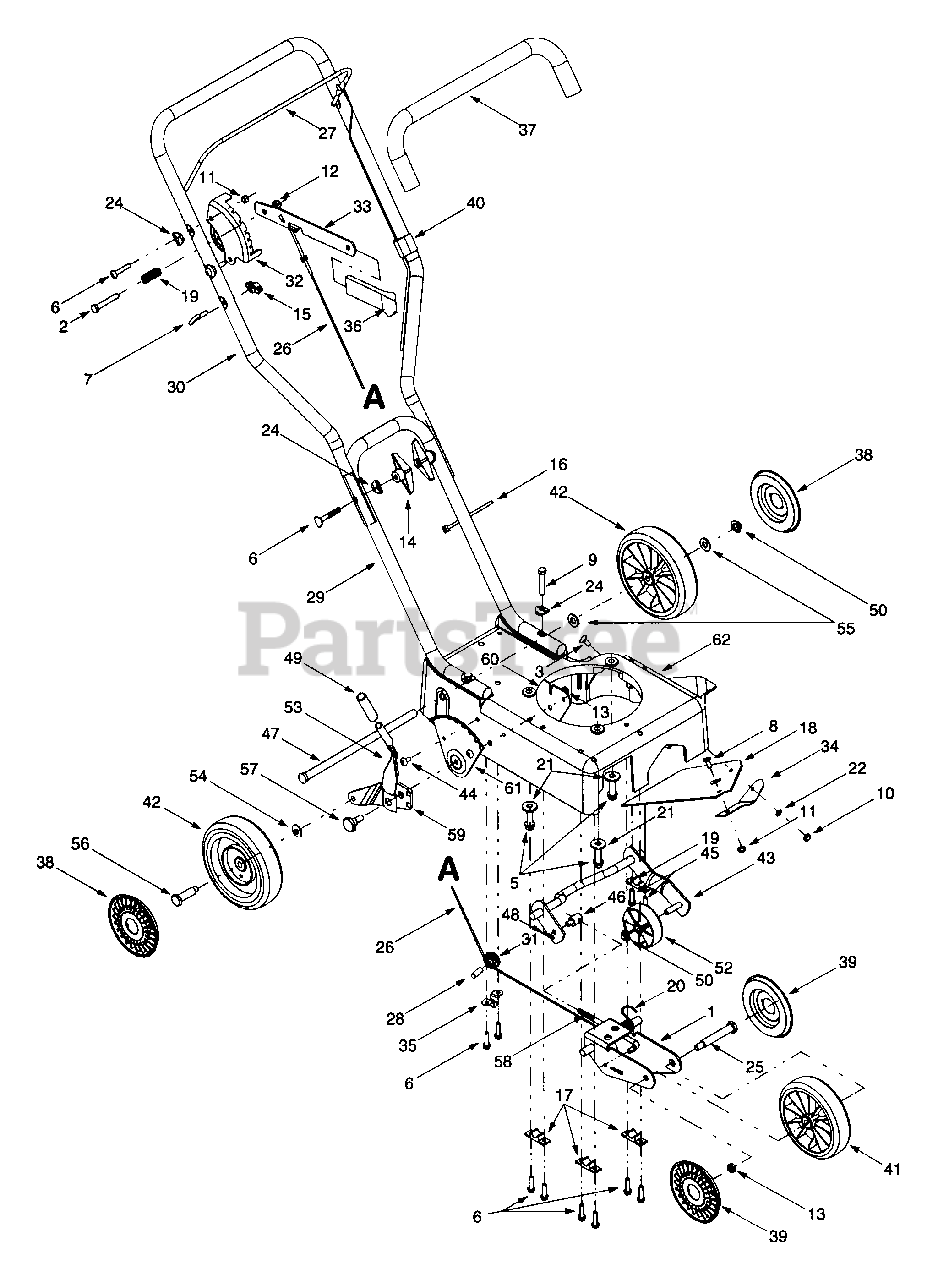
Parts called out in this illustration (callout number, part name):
1	Front Wheel Bracket Assembly
2	Hex Cap Screw, 5/16-18 x 2.0
3	Carriage Screw, 1/4-20 x .625
5	Sems Screw, 3/8-16 x 1.5
6	Carriage Bolt, 5/16-18 x 2.0
7	Eye Bolt (Rope Guide),1/4-20
8	Hex Cap Screw, 1/4-20 x.5
9	Hex Cap Screw, 5/16-18 x 1.75
10	Hex Nut, 1/4-20
11	Hex Lock Nut, 1/4-20
12	Hex Lock Nut, 5/16-18
13	Jam Lock Nut, 3/8-16
14	Wing Knob, 5/16-18
15	Wing Knob, 1/4-20
16	Cable Tie
17	Block Bushing, .515 x .62
18	Discharge Deflector Shield
19	Compression Spring, .55 x 1.37
20	LH Torsion Spring, .655
21	Flat Washer, .385 x 1.0 x .135
22	Lock Washer, 1/4
24	Saddle Washer, .320 x.93
25	Shoulder Screw, 3/8-16, .5 x 2.62
26	Depth Index Cable, 44.5"
28	Cable Roller Rod
32	Depth Index Bracket
34	Discharge Deflector Keeper
37	Foam Grip, 22"
38	Hub Cap, 5.75"
39	Hub Cap w/ Center Hole, 5.75"
40	Control Cable w/ Clip, 31.75"
41	Link Tread Wheel w/ BB,7 x 2
42	Link Tread Wheel w/ BB, 8 x 2
45	Hi-Lo Tap Screw, 1/4-15 x 1.0
46	Ferrule, 5/16-24 s .312
47	Curb Axle
48	Internal Cotter Pin
49	Height Adjuster Grip, 2.5"
50	Push Cap, 3/8
52	Curb Support Roller
53	Height Adjuster Spring Lever
54	Bell Washer, .401 x .870 x .063
55	Flat Washer, .510 x 1.0 x .125
56	Shoulder Screw, 3/8-16, .49 x 1.4
57	Shoulder Screw, .50 x .434
58	Link Rod, 5/16-24
59	Curb Wheel Pivot Arm
60	Curb Wheel Back Plate
61	Curb Wheel Adjuster Plate
62	Edger Base Assembly
